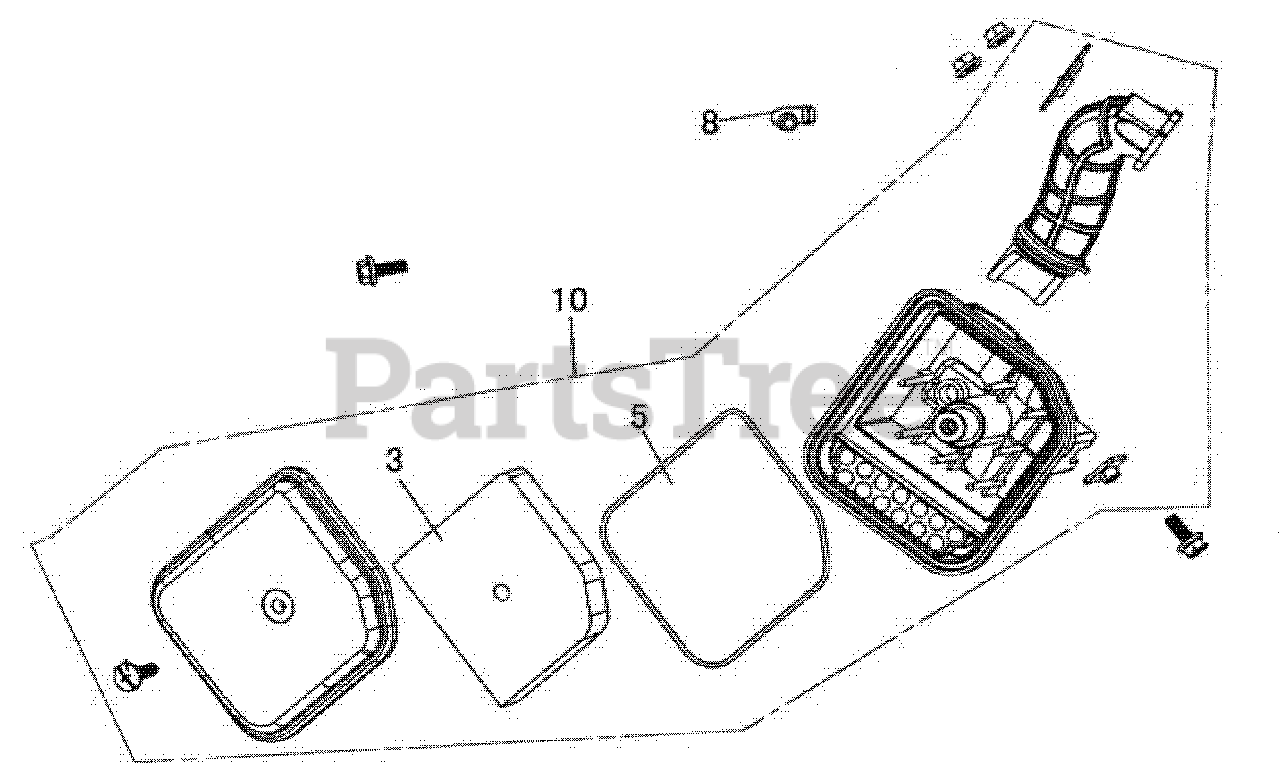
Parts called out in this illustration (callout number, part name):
3	SPONGE, SPARSITY
5	SEAL, AIR CLEANER
8	TIE-IN TUBE, BREATHER
10	AIR CLEANER ASSY
